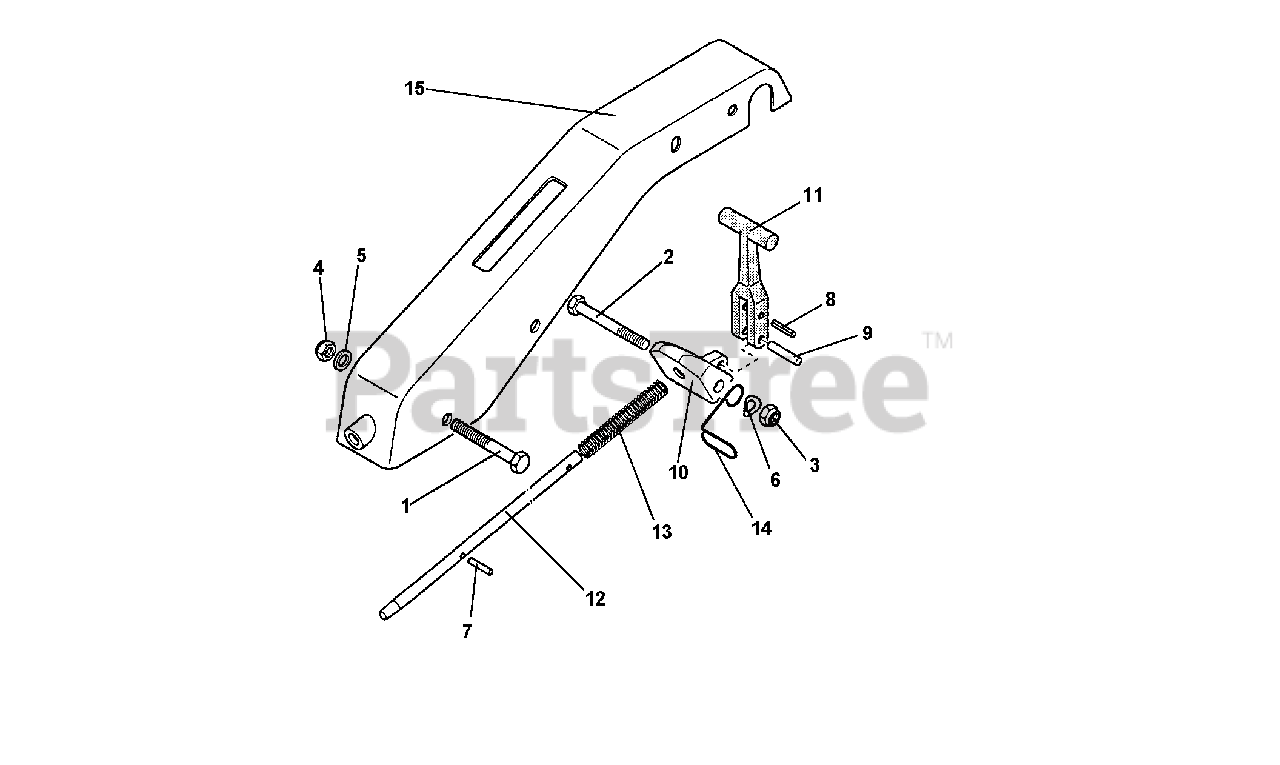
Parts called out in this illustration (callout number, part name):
1	SCREW, M12X85
2	SCREW, M10X80
3	NUT, SELF LOCKING, M10
4	NUT, SELF LOCKING, M12
5	WASHER, M10.4
6	WASHER, LOCKING, M13
7	PIN, LOCKING
8	PIN, LOCKING, M4X35
9	PIN, LOCKING
10	SUPPORT, RD
11	ADJUSTING LEVER
12	HANDLEBAR POSITION ROD
13	SPRING, ROD
14	CABLE GUIDE
15	STEERING COLMUN
